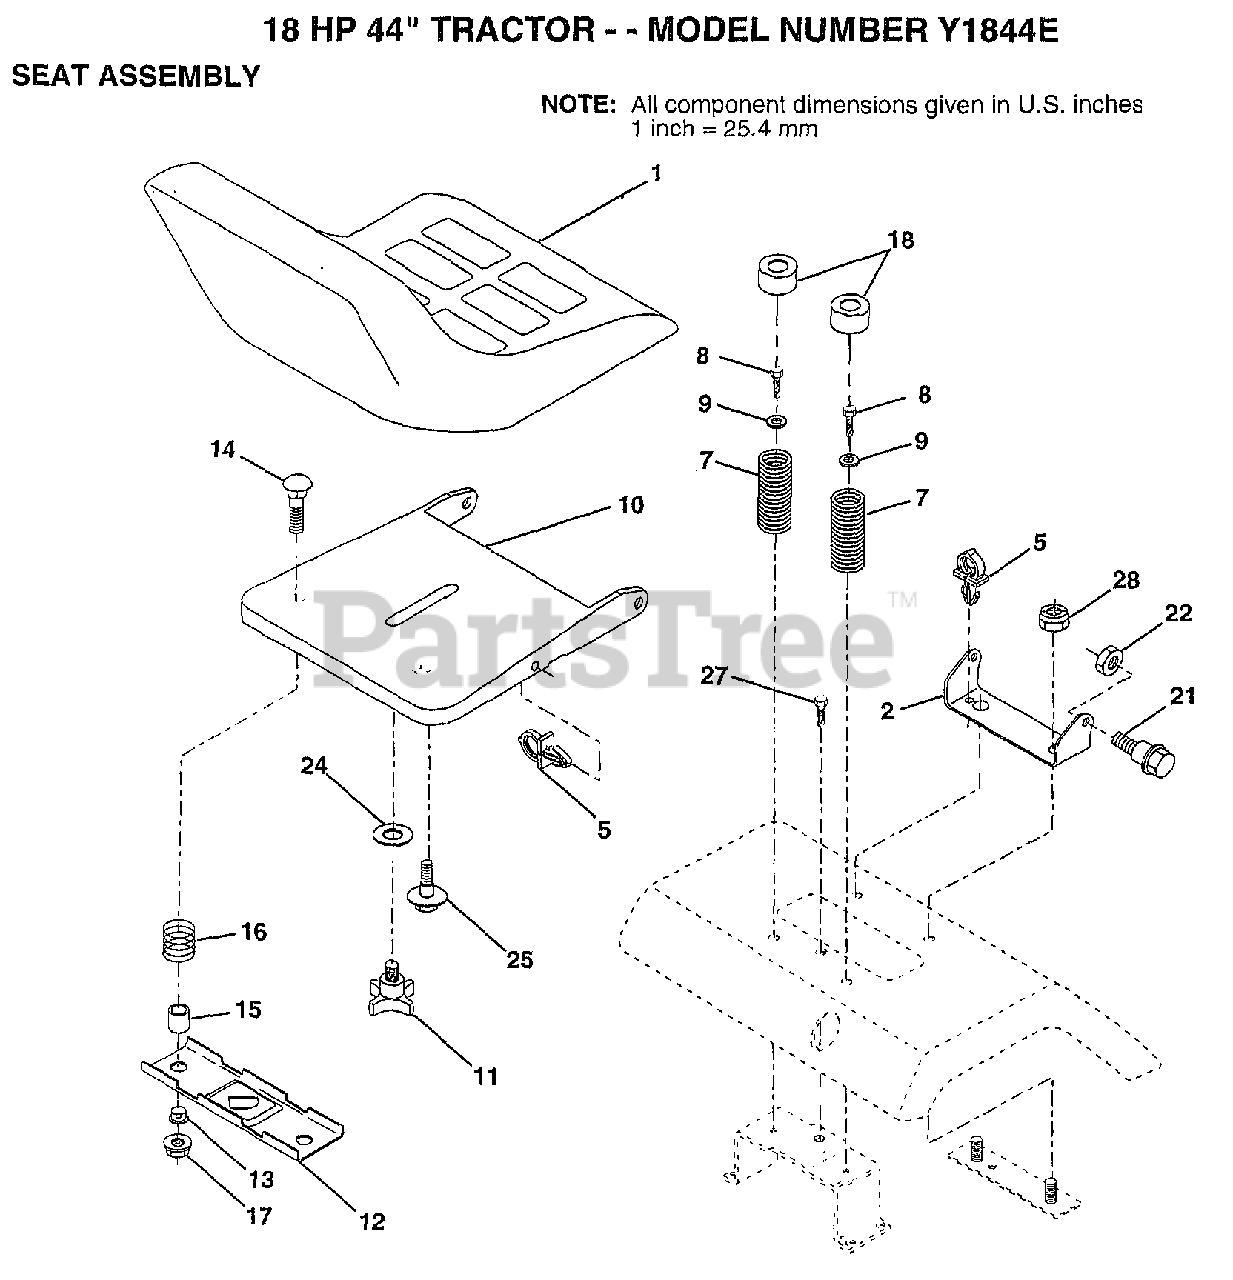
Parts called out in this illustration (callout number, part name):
2	BRACKET PVT SEAT
5	CLIP.PUSH-IN.HING
7	SPRING COMPRESSIO
8	SCREW LT
9	WASHER
11	"KNOB 1/2"" YT"
12	BRKT SWITCH
13	BUSHING
15	SPACER SPLIT
16	SPRING COMPRESSED
18	CAP SPRING
21	BOLT.SHLD.5/16-18
24	WASHER
25	"BOLT,SHOULDER"
27	SCREW LT
